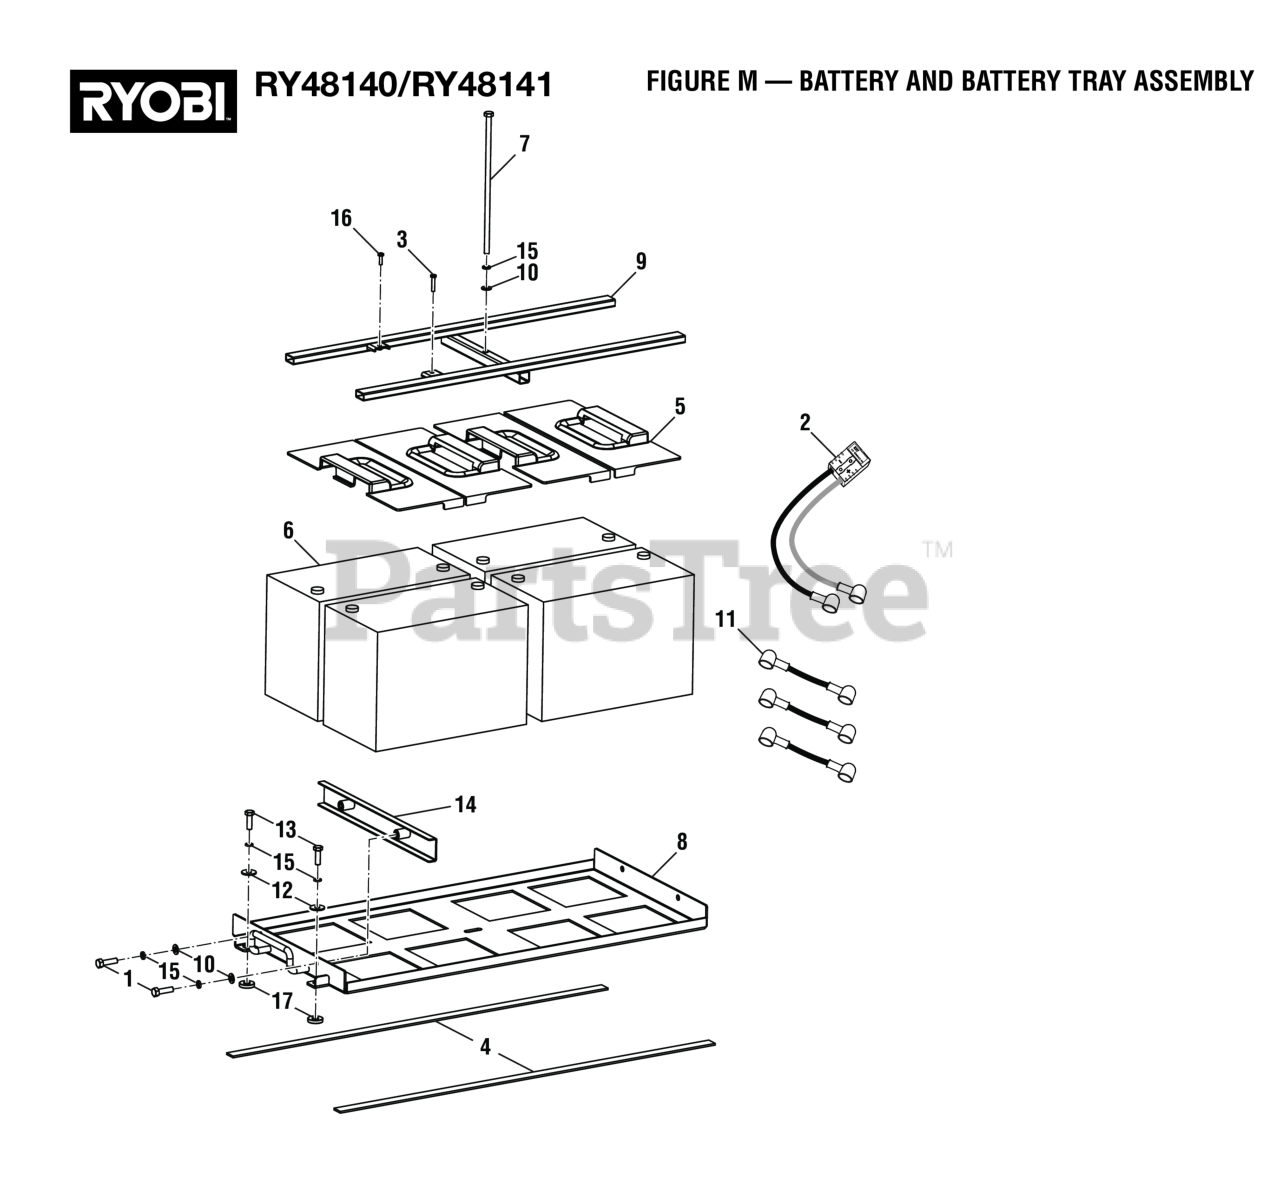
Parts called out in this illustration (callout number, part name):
1	Bolt (M8 x 25 mm)
2	Battery Cable 2, ZTR
3	Screw (M5 x 25 mm)
4	Battery Tray Slider
5	Battery Shield, ZTR
6	LPC12-115 Battery
7	Hex Bolt (M8 x 240 mm)
8	Battery Tray
9	Battery Tie Down
10	Washer (OD16 x ID8.4 x 1.6t)
11	Battery Cable w/Covers (Red and Black, 120 mm)
12	Washer (OD 24 x ID8.4 x 2t)
13	Bolt (M8 x 25 mm, Hex Hd.)
14	Battery Holder Bracket
15	Lock Washer (OD9.8 x ID8.5 x 5t)
16	SCREW,PPHMS, M5 X 0.8 X 16 - STEEL,
17	Metal Bushing
